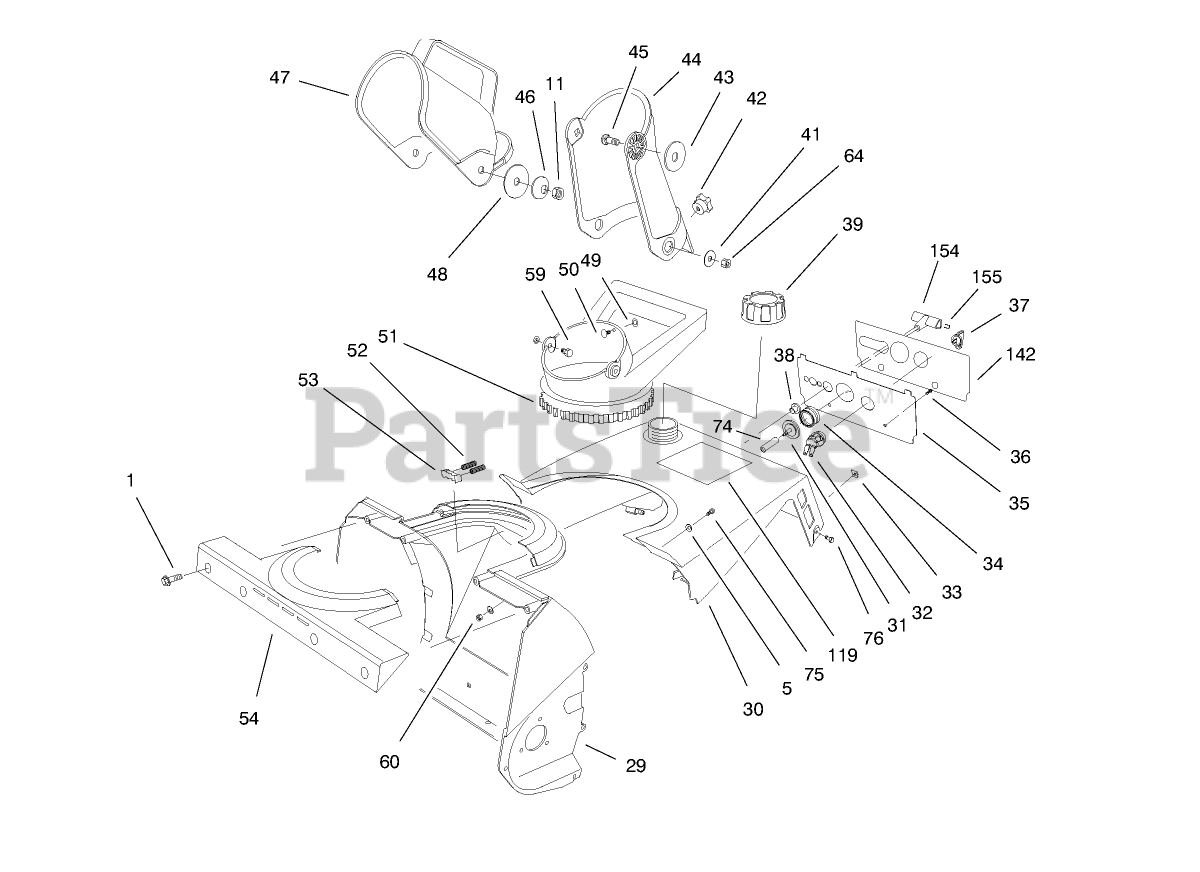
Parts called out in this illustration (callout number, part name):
1	SCREW-PLASTIC
5	WASHER-FLAT
11	NUT-LOCK, NI
29	HOUSING
31	BODY-PRIMER
32	SWITCH
34	BULB-PRIMER
36	SCREW-SHWH, THREAD FORMING
37	KEY-IGNITION
38	GUIDE-ROPE, STARTER
41	WASHER-FLAT
42	KNOB-CHUTE
43	WASHER-RUBBER
45	BOLT-CARR
46	WASHER-BELLEVILLE
47	DEFLECTOR-CHUTE
48	WASHER-FLAT
49	PUSHNUT-RETAINER, BOLT
50	SCREW-CARR
51	HANDLE-CHUTE
52	SPRING-COMPRESSION
53	DETENT-CHUTE
54	RETAINER-CHUTE
59	SCREW-HH
60	NUT-LOCK, NI
64	NUT-LOCK, NI
74	HOSE-PRIMER
75	SCREW-PPH
76	SCREW-THREAD FORMING
154	HANDLE-STARTER
155	STAPLE-HANDLE
